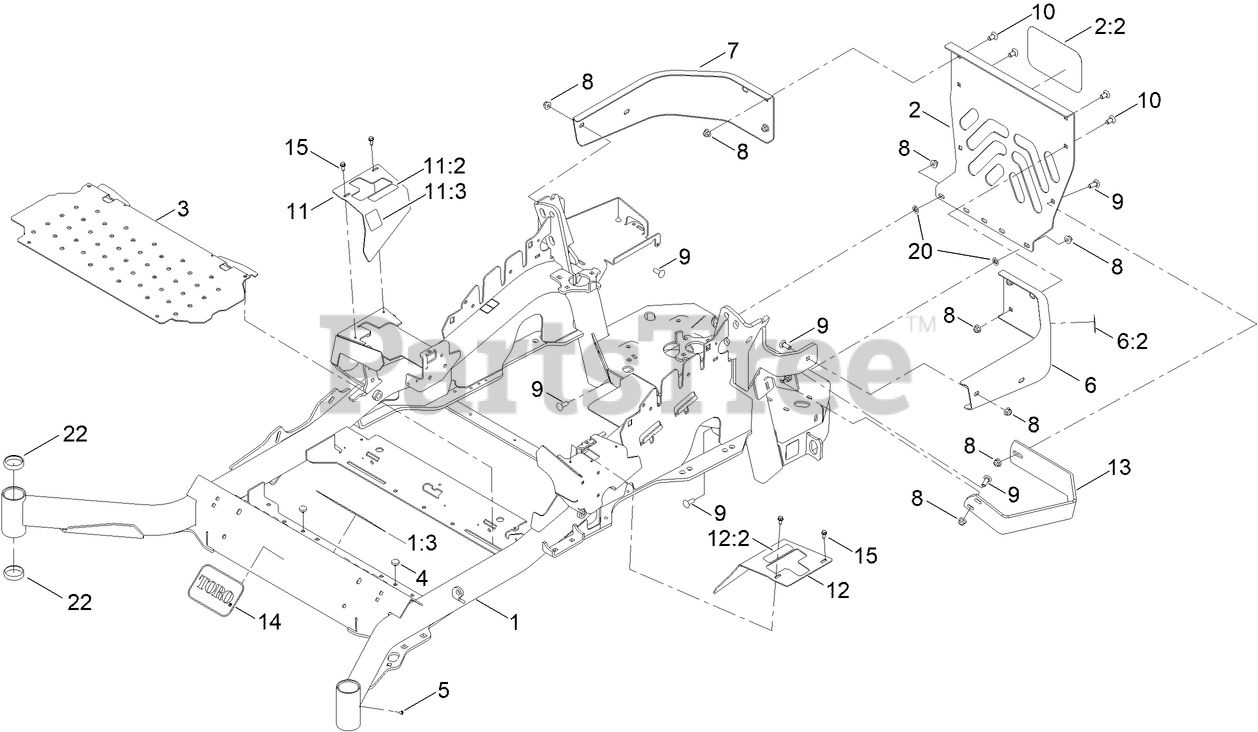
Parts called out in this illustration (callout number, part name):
1	MAINFRAME ASM
1:3	DECAL-DANGER
2	REAR GUARD ASM
2:2	DECAL
3	FLOORPAN
4	BUMPER
6	LH BUMPER ASM
6:2	DECAL-WARNING
7	BUMPER-RH
8	NUT-HF, NI
9	SCREW-CARR
10	SCREW-CARR
11	RH MOTION CONTROL COVER ASM
11:2	DECAL-CONTROL, MOTION
11:3	DECAL-PARK BRAKE, CE
12	LH MOTION CONTROL COVER ASM
12:2	DECAL-CONTROL, MOTION
13	GUARD-MUFFLER
14	DECAL
15	SCREW-HWH
20	NUT-PUSH
22	CUP-BEARING
